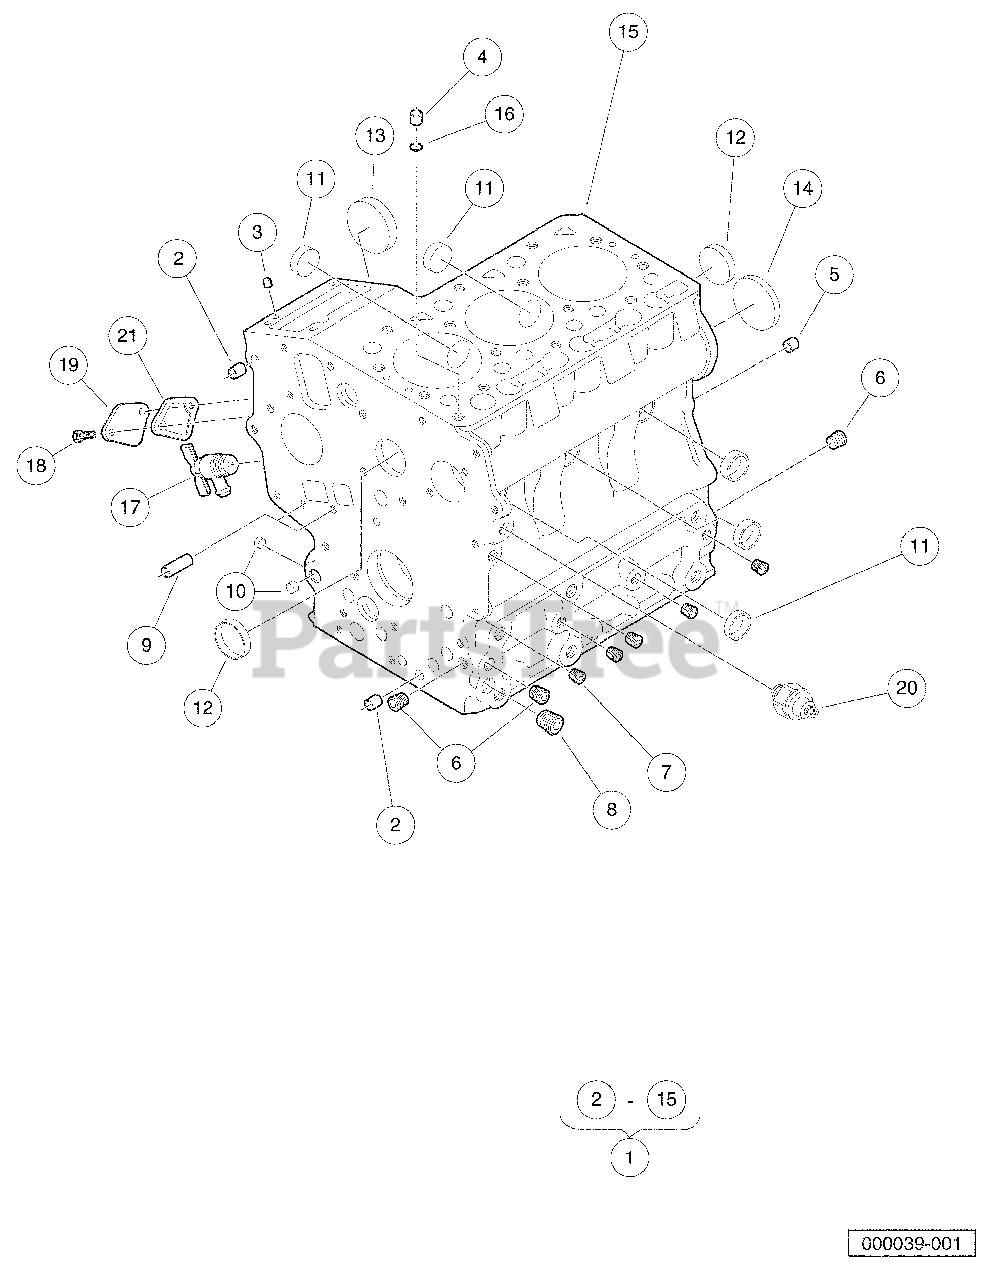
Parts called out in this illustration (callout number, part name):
1	Engine Block
2	Pin, Pipe, Dia 8 X 14
3	Pin, Straight, Dia 5 X 10
4	Pin, Pipe, Dia 7 X 14
5	Pin, Straight, Dia 8 X 16
6	Plug, 1/8"
7	Plug, 3/32"
8	Plug, 1/4"
9	Pin, Pipe, Dia 8 X 11
10	Cap, Sealing, Small
11	Cap, Sealing, Med
12	Cap, Sealing, Large
13	Cover, Fuel Camshaft
14	Plug, Expansion
15	Block, Engine
16	O Ring, 8 X 7
17	Cock, Drain
18	Bolt, M6 X 1 X 20
19	Plate, Engine Block
20	Switch, Oil Pressure
21	Gasket, Fuel Pump, D722
